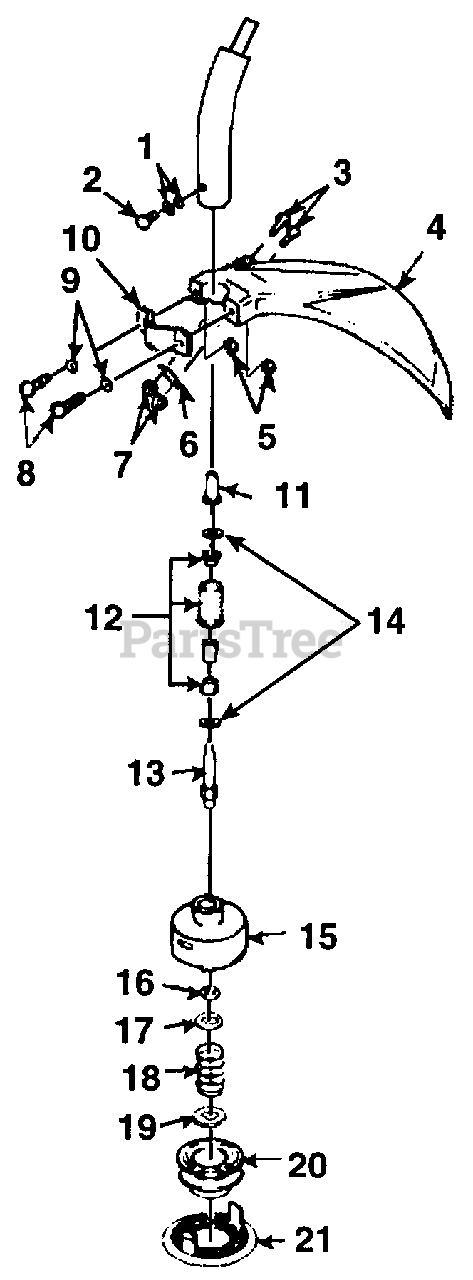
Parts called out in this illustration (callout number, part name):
2	Screw
3	Screw
4	Deflector
5	Nut
6	Blade, Cut-Off
7	Nut
8	Screw
10	Bracket Clamp
11	Adapter, Arbor
12	Bushing Assembly
13	Arbor Post
14	Thrust Washer
15	3" Head Body
17	Plate, Spring
18	Spring
19	Plate, Spring
21	3" Head Cap
